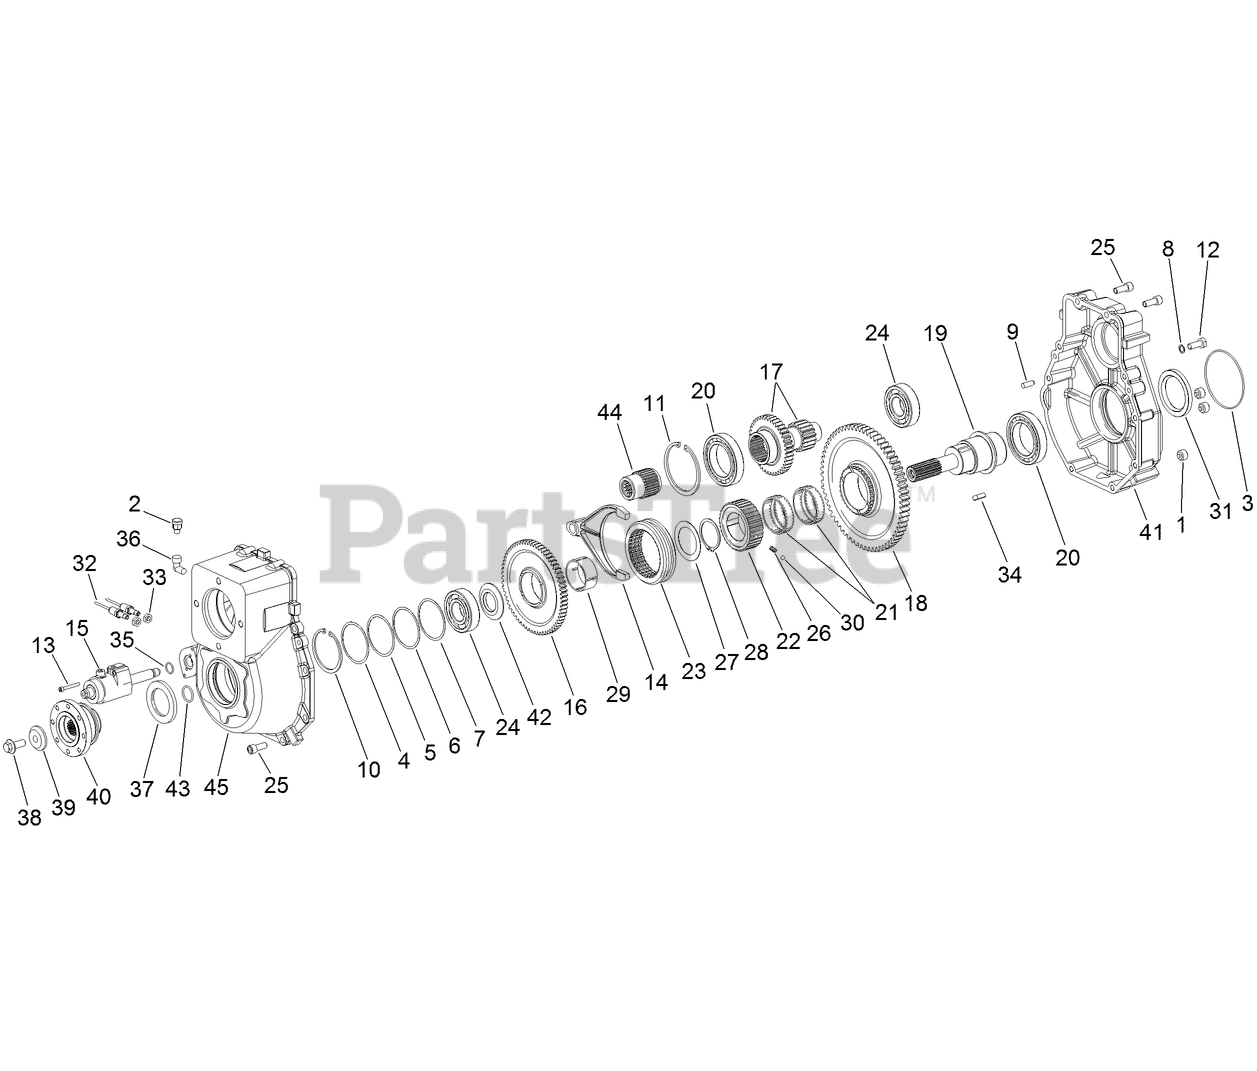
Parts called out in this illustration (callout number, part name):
1	PLUG-MAGNETIC
2	PLUG-BREATHER
3	O-RING
4	SHIM (0.35)
5	SHIM (0.5)
6	SHIM (0.4)
7	SHIM (0.3)
8	WASHER-SCHNORR
9	PIN-PARALLEL
10	RING-RETAINING
11	RING-SNAP
13	SCREW-HSH
14	FORK-GEARBOX
15	CYLINDER-GEARBOX
16	GEAR-DRIVEN
17	GEAR-DRIVE
18	GEAR-DRIVEN
19	SHAFT-DRIVEN
20	BEARING-BALL
21	CAGE-BEARING, NEEDLE
22	HUB-SELECTOR
23	COLLAR-SHIFT
24	BEARING
25	SCREW-HSH
26	SPRING-SELECTOR
28	RING-SNAP
29	BEARING-NEEDLE
30	SPHERE
31	SEAL-OIL
32	SENSOR-SELECTOR, GEAR
35	O-RING
36	ELBOW-90 DEG
37	SEAL-OIL
38	SCREW-FLANGED
39	WASHER-PINION
40	FLANGE-PTO
41	HOUSING-GEAR
42	SHIM-GEAR
43	O-RING
44	SLEEVE-MOTOR
45	COVER-GEAR
